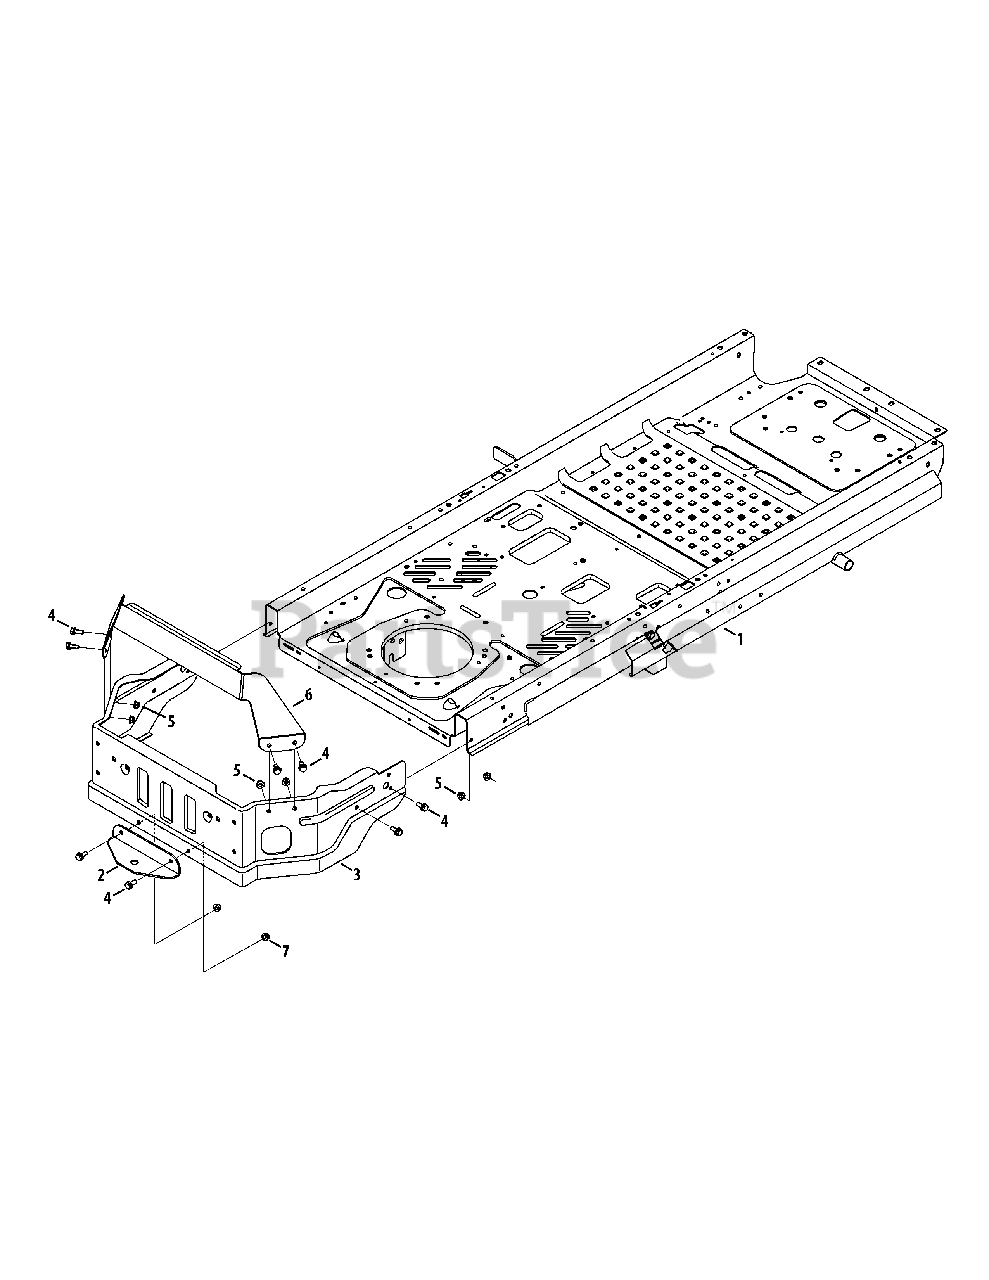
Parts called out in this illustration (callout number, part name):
1	Frame Assembly
4	Screw, 5/16-18, Hexflange
5	Flange Lock Nut, 5/16-18
6	Upper Bumper Bracket
7	Flange Counter Lock Nut, 5/16-18
